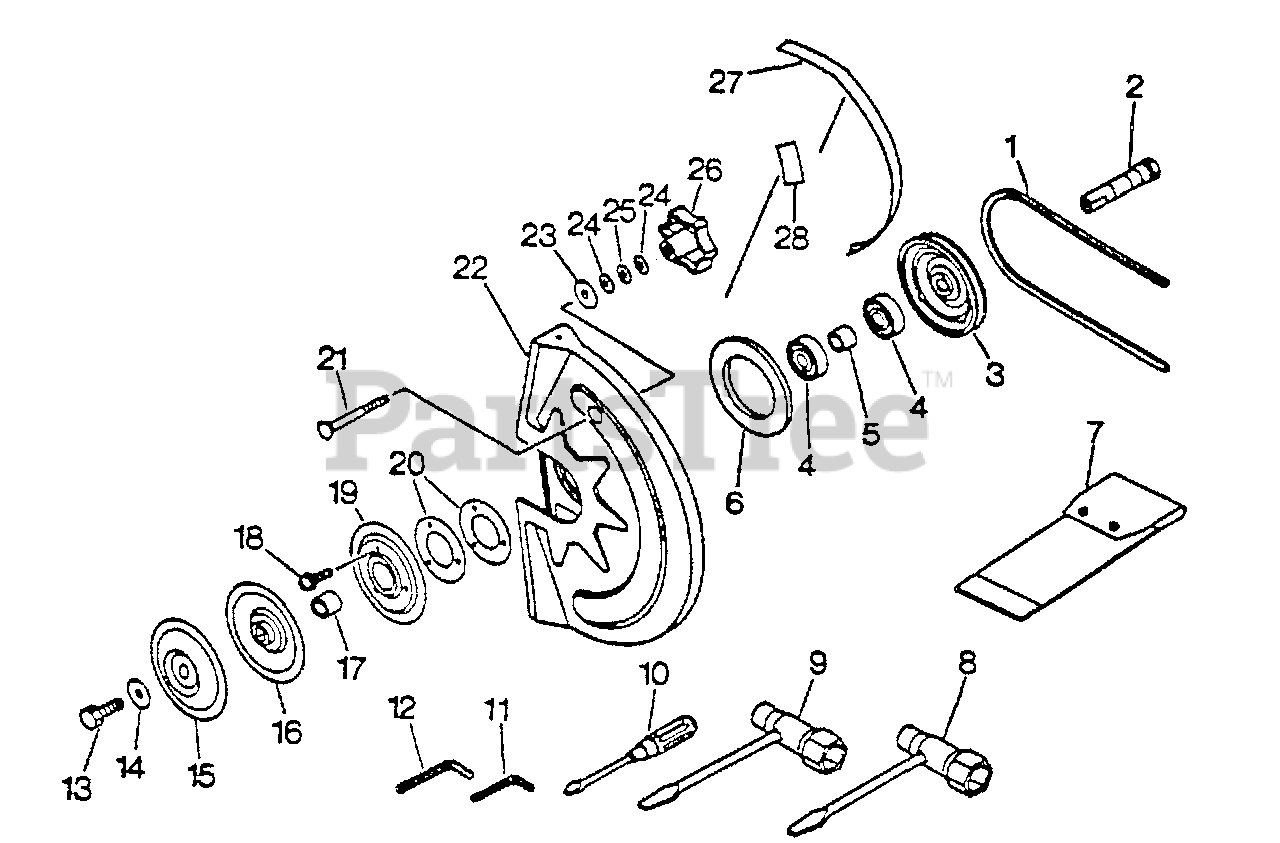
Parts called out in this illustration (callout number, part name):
4	BEARING, BALL - 6203
5	SPACER
7	BAG, TOOL
8	T-WRENCH - 13X19mm
9	T-WRENCH - 17X19mm
10	SCREWDRIVER
11	HEX KEY - 4mm
12	HEX KEY - 5mm
15	FLANGE, CUTTER
16	FLANGE, CUTTER
18	SCREW - 4X14
19	PLATE, CUTTER COVER
21	BOLT - 10X70
22	COVER, BLADE
24	WASHER - 10
25	LOCKWASHER - 10
27	LABEL - MARK
28	LABEL - ECHO
